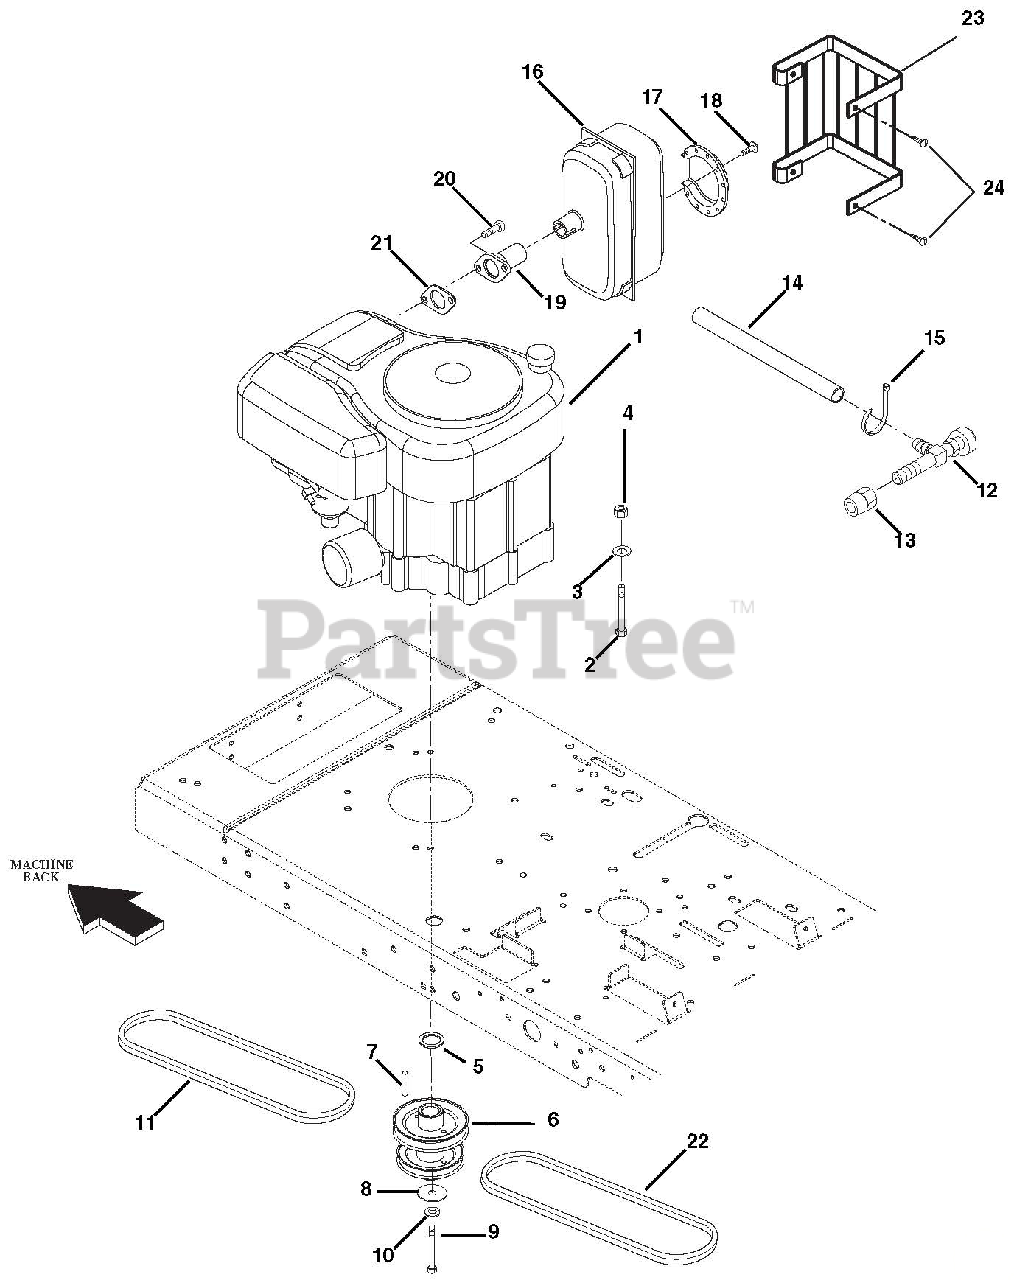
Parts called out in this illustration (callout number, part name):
1	ENGINE, B&S INTEK SINGLE 17HP
2	@BLT-HEX .31-18X1.50 GR5 YWZC
3	WSHR-FL-STL .328X1.0X.094 YWZC
4	@NUT-LK-NYL .312-18 YWZC
5	SPACER 1.09 X 1.50 X .105
6	ENGINE SHEAVE 4.50
7	KEY-SQ .25 X 2.50 X .25 SAE
8	WSHR-FL-STL .469X2.00X.25 YWZC
9	BLT-HEX .44-20X3.00 GR5 YWZC
10	@WSHR-LK .44X.109 REG YWZC
11	V-BELT, 4L-RAW EDGE
12	COCK, OIL DRAIN
13	ADAPTER, OIL DRAIN
14	TUBE OIL DRAIN
15	CABLE TIE LG 5-1/2
16	MUFFLER B&S
17	DEFLECTOR B+S 222573
18	SCREW B+S 93705
19	MUFFLER ADAPT. PIPE B+S 496656
20	SCR-CAP .31-18X.75 S/HD
21	GASKET B&S#272293
22	V-BELT, HB-WRAPPED
23	GUARD, MUFFLER
24	@SCR-TAP .25-20X.37 HWH YWZ TR
